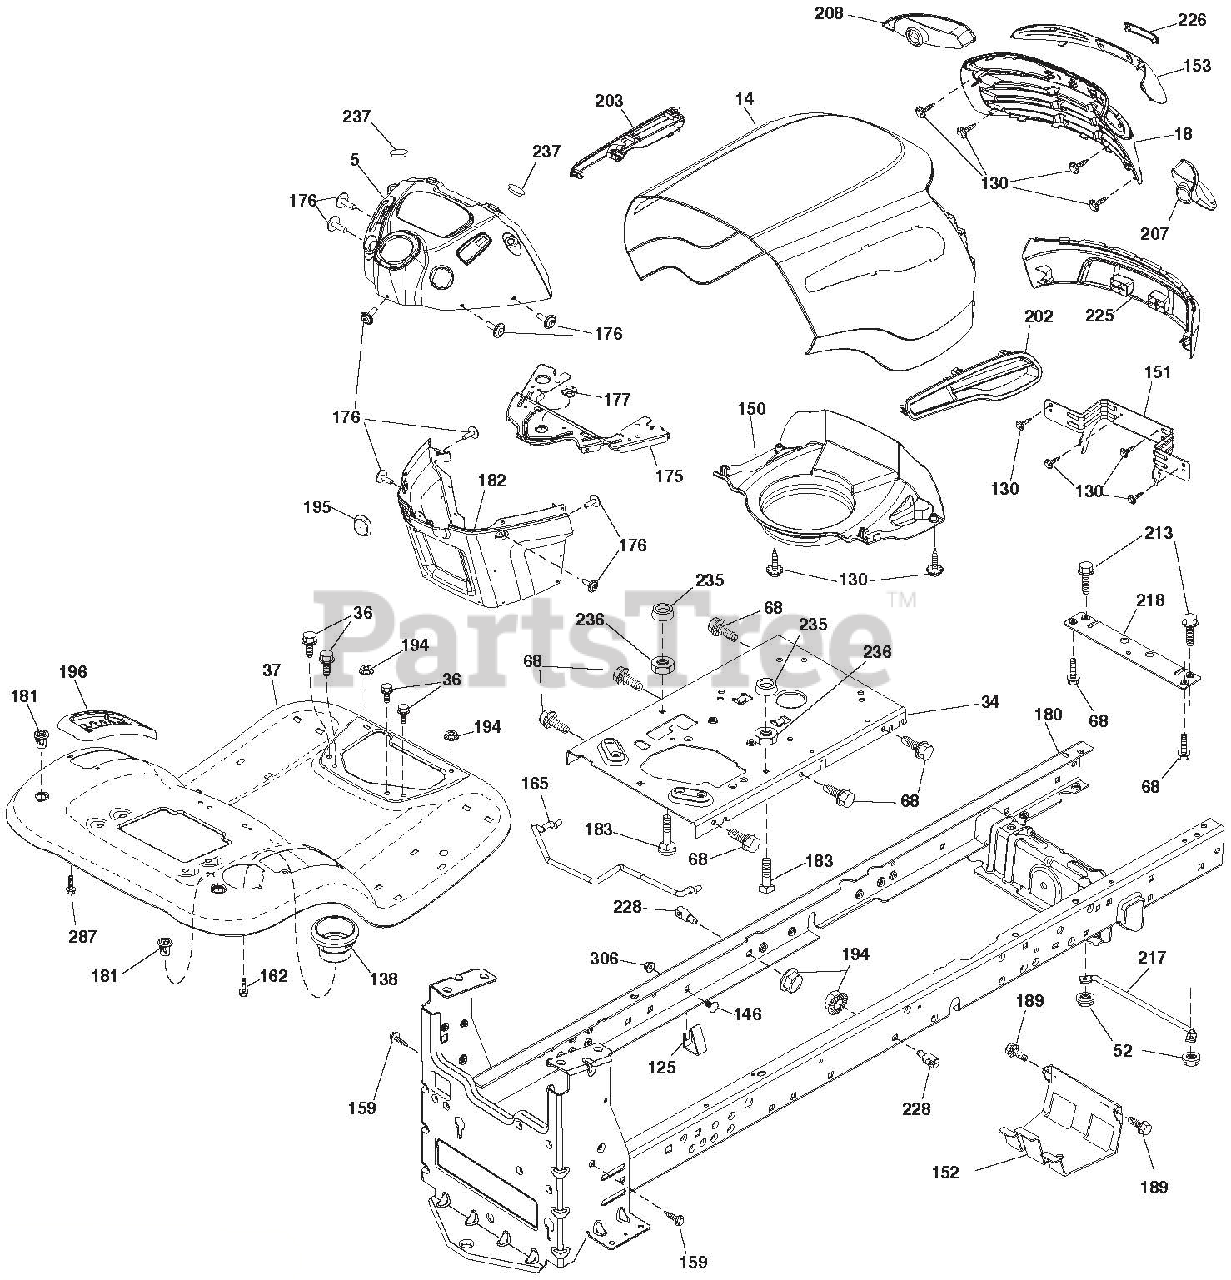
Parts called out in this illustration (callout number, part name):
5	DASH P/L TEX CABLE
18	GRILLE.ELITE.ARIENS.BLACK
34	PLATE.ENGINE.WELDED.CHASSIS
36	SCREW.5/16-18X3/4.SMGML.TAP/R
37	FENDER.TLT W/CPH
52	Nut, Hex, Crownlock 5/16-18
68	SCREW.THDROL.5/16-18 X 1/2TYTT
125	CLIP.FUEL.LINE
138	CUPHOLDER TL TEX 428
150	AIR DUCT
151	BRACKET.PIVOT
152	SHIELD.BROWNING.W/TEX
153	LENS.BAR
159	SCREW.HEXWSH THDR3/8-16X3/4.BL
162	SCREW.HEX.WSH.HI-LO.1/4X1/2UNC
175	CROSSMEMBER.LT
176	SCREW.#10-24X5/8.RND.QUDRX.GIM
177	BUSHING.STEERING.LT
180	CHASS WLDMT TL 12 GA/2PC 18/22
181	BUSHING MNT FEND CRGO BLK TEX
182	DASH.LOWER.LT.CCS
183	BOLT.FIN.HEX.5/16-18 UNC X1-1/
189	SCREW.5/16-18X3/4.SMGML.TAP/BL
194	Nut, Lock Hex Flange 5/16-18 u
195	PLUG HOLE DASH TOWER
196	CONSLE.ASM.DECK.LFT.BL/RBT.TLT
202	VENT RH
203	VENT.SIDE.LH
207	BEZEL.RH
208	BEZEL.LH
213	Bolt, Hex Head 5/16-18 x 3/4
217	ROD.PIVOT.HOOD
218	X-PIECE.HOOD.STOP.NON/STEALTH
226	ARIENS.LOGO.PLATE
228	STUD.FASTNER.W/'D'ANTI-ROTATIO
235	SPACER.FENDER
236	NUT.CENTER LOCK.5/16-18 UNC
237	PLUG.MOUNT.CARGO
287	SCREW.HEX.WASHEAD.1/4-20 X 3/8
306	Nut, Hex, Flangelock 3/8-16
